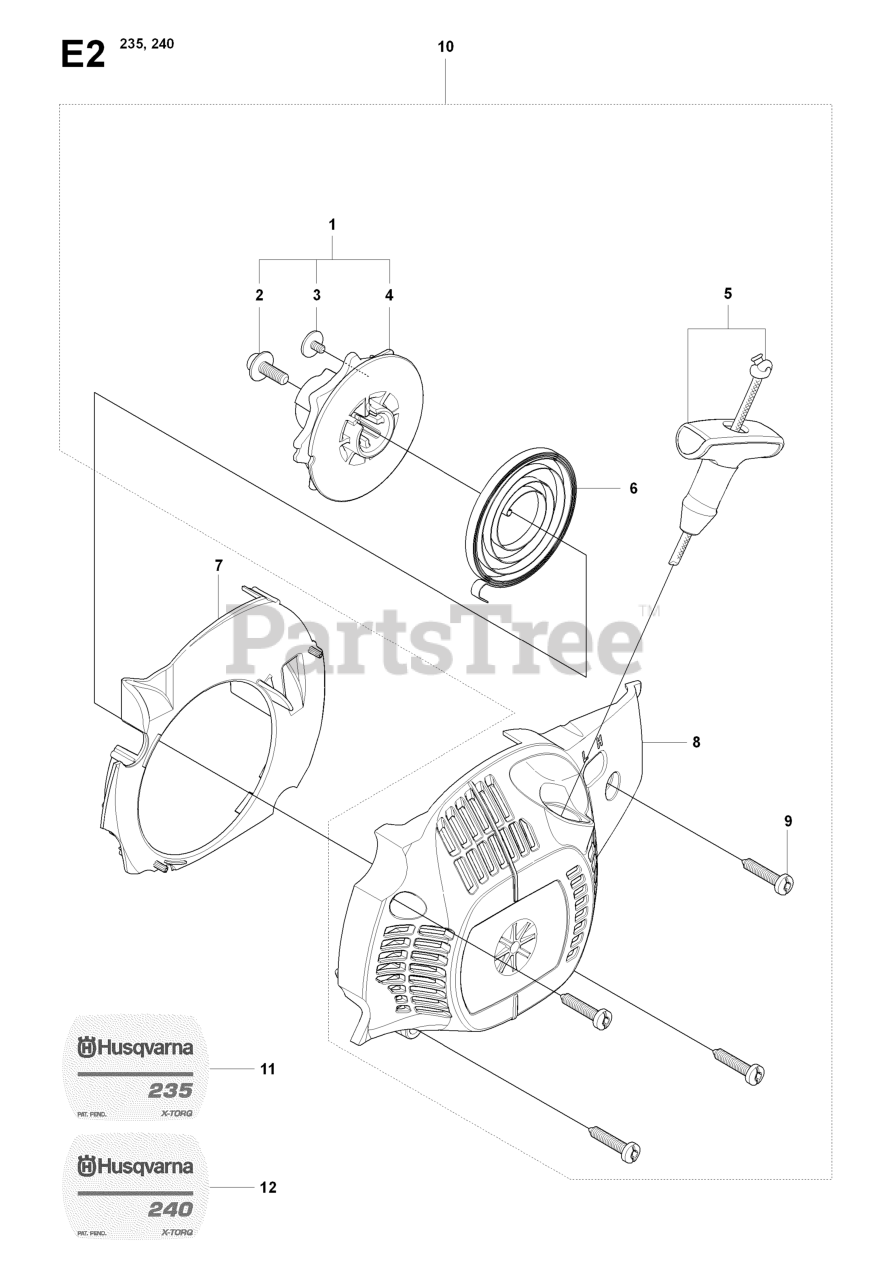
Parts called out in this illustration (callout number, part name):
1	KIT, STD STARTER
4	STARTER PULLEY
5	STARTER ROPE W/HANDLE
6	SPRING STARTER
8	FAN HOUSING
9	SCREW M5.38-14X22.225MM
10	STARTER KIT COMPLETE 235/240
